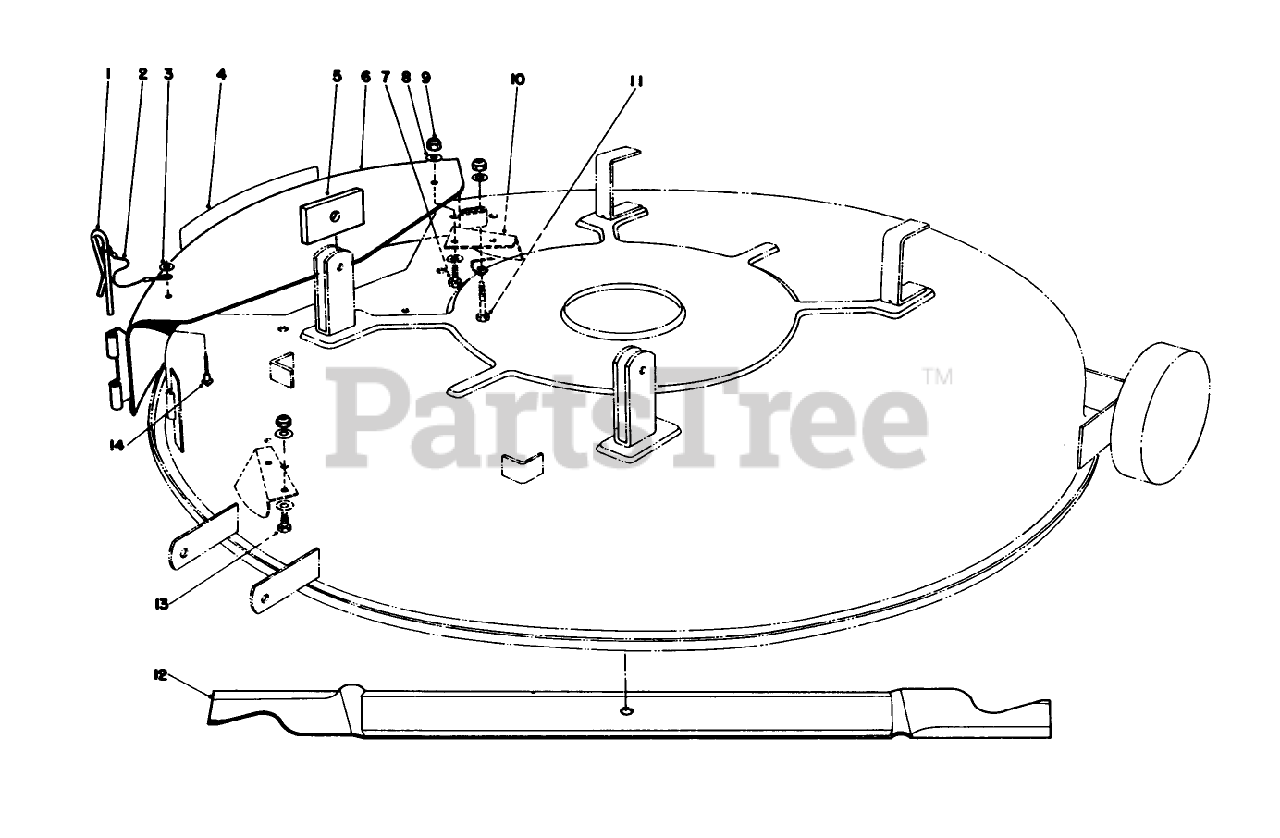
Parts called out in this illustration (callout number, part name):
1	PIN-LOCKING, CHUTE
2	LANYARD
3	WASHER-PLAIN
6	MULCHER COVER ASM (BLACK)
7	SCREW-HH
8	WASHER-PLAIN
9	NUT-LOCK, NI
10	KICKER *B
11	SCREW-HH
13	SCREW-HH
14	RIVET-BLIND
